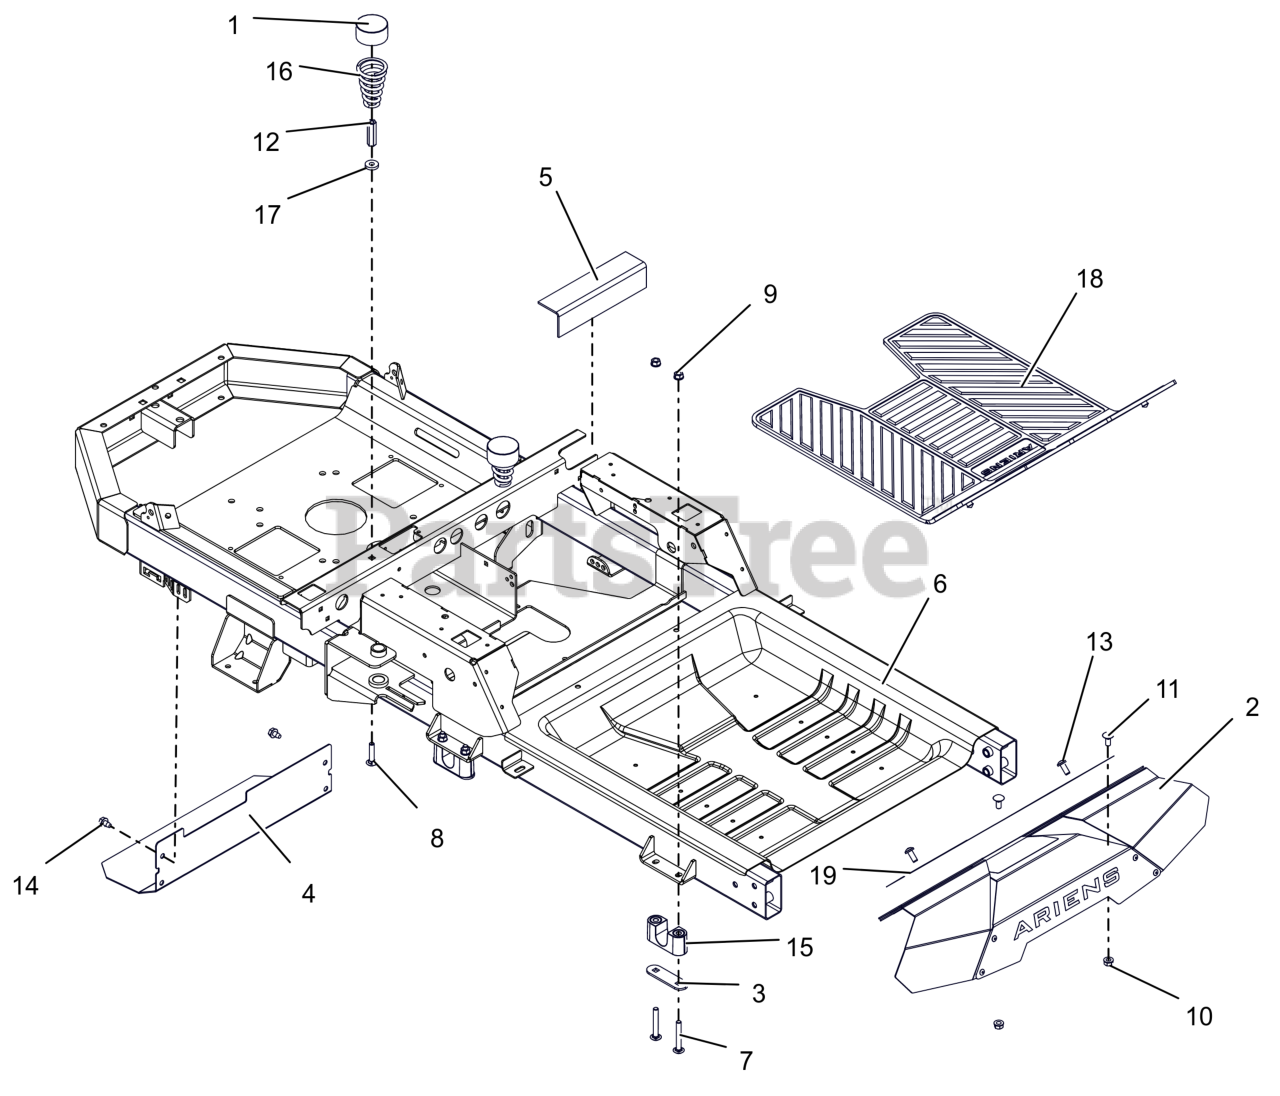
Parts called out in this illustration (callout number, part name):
1	HUB CAP
2	KIT, IKON FOOT REST W/DECAL
3	PLATE, BEARING SUPPORT
4	HEAT, SHIELD
5	PAD, RUBBER-TANK
6	KIT, IKON-X/XL FRAME (2016)
7	BLT, RHSSN.31-18X2.25 G5 ZCC
8	BLT,RHSN .31-18X1.50 G5 ZCC
9	NUT,LK-CTR-FLG .31-18 GF ZCC
10	NUT-LK-TOP-FLG .312-18 GF ZCC
11	BLT,RHSN .31-18X.75 G5 ZCC
12	NUT, COUPLING .31-18X1.75 ZCC
13	SCR-RDHDSKTAP .31-18X.75 ZCC
14	SCR,TAP .312-18X.50 HWH TR ZCC
15	BSHG, DECK LIFT PIVOT
16	SPRING, SEAT
17	WSHR, FLT .328X.870X.179 ZCC
18	FLOOR MAT, RUBBER-ARIENS XL
19	GRIP TAPE, FOOT PLATE
